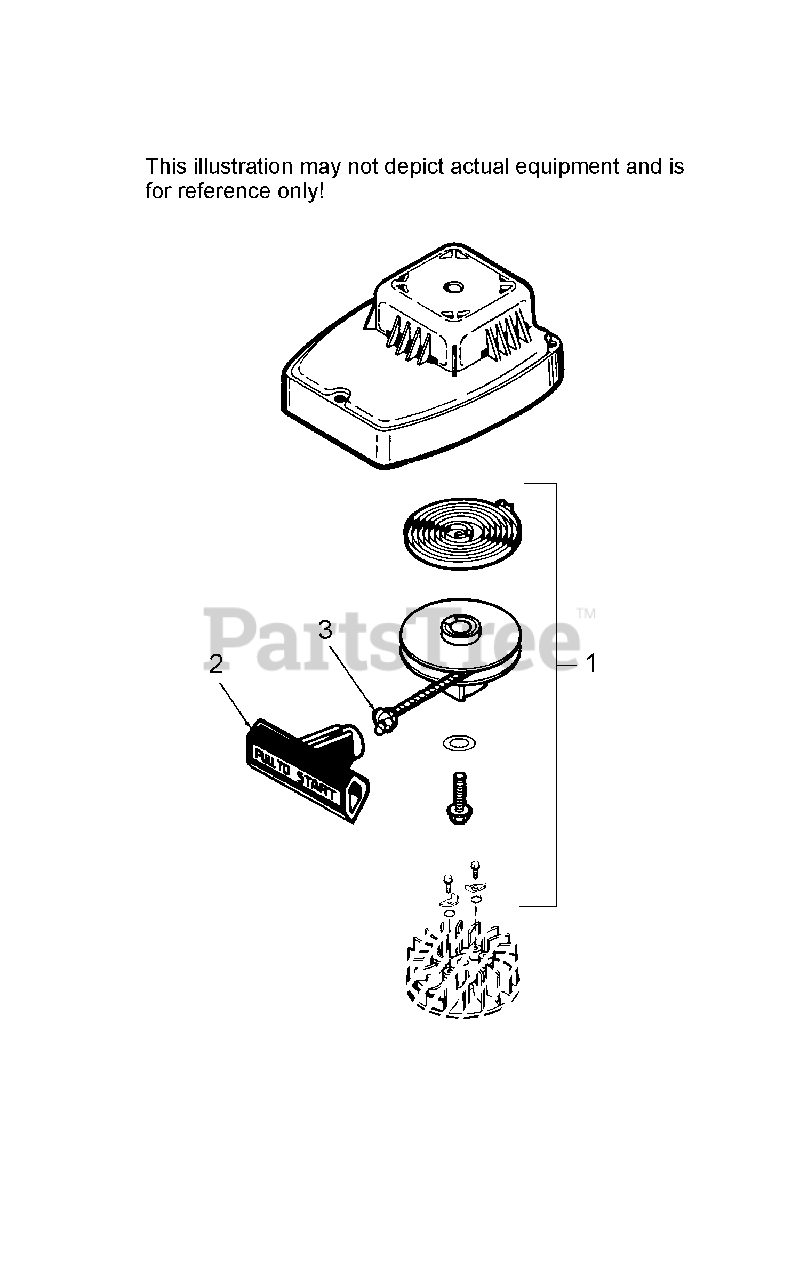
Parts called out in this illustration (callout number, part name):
1	Retainer Screw, 10-24 x 1/2"
3	Pawl Screw, 12-24 x 11/64"
4	Flat Washer
5	Pawl Spring
6	Starter Pawl
8	Starter Pulley
9	Rewind Spring
12	Starter Rope (42.5")
13	Starter Handle
